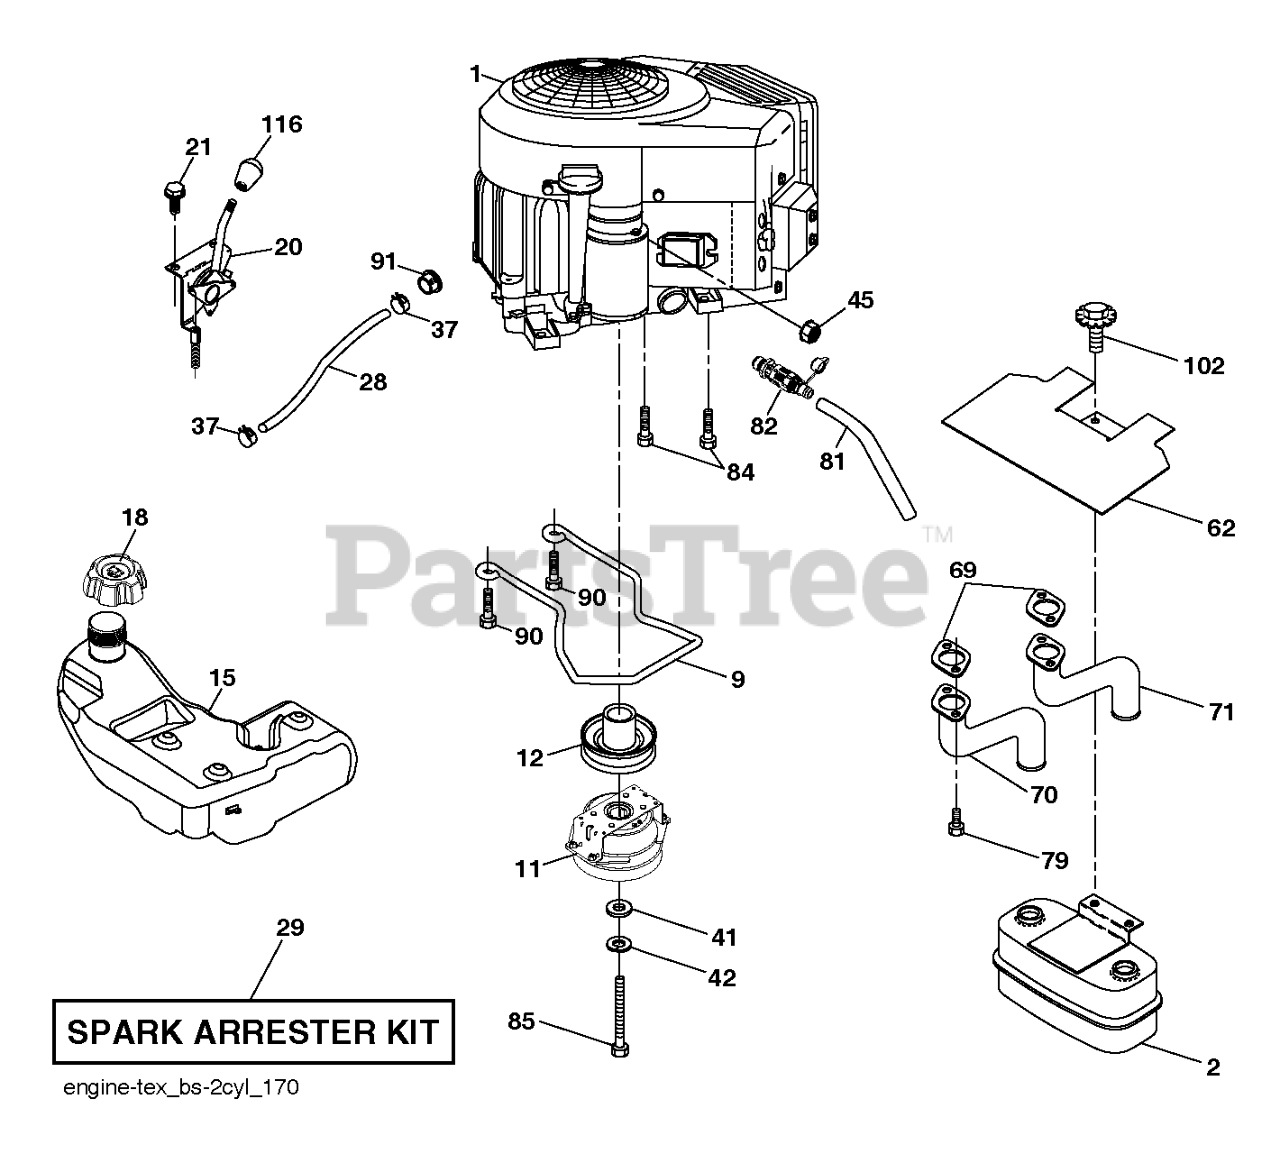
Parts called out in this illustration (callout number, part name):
2	MUFFLER.ASM.TWIN.MNTG.BRACKET
9	KEEPER.BELT.ENG.4.25"2.BLT.431
11	CLUTCH.OGURA.5.0PD.GT1.5A-EH07
12	PULLEY.ENGINE.TUFFTORQ
15	FUEL.TANK.ASM.3.0GAL.REAR.2019
18	CAP ASSY FUEL 3" GRAY
20	THROTTLE.PRO.RSTART. 38
28	LINE.FUEL.64"REAR.EMIS
29	KIT.SPARK ARRESTOR 794945 B&S
37	HOSE CLAMP
62	SHIELD.HEAT.MUFFLER
69	GASKET.MUFFLER
70	EXHAUST.TUBE.RH.B&S.TWIN.INTEK
71	EXHAUST.TUBE.LH.BS/TWIN
81	TUBE, DRAIN OIL ASM.
82	VALUE.OIL.DRAIN
84	SCREW.3/8-16
85	BOLT.HEX.7/16-20X3.75.GR5.RED
90	SCREW 3/8-16X1
91	BUSHING.1.375OD
102	SCREW
116	KNOB - SHIFT
